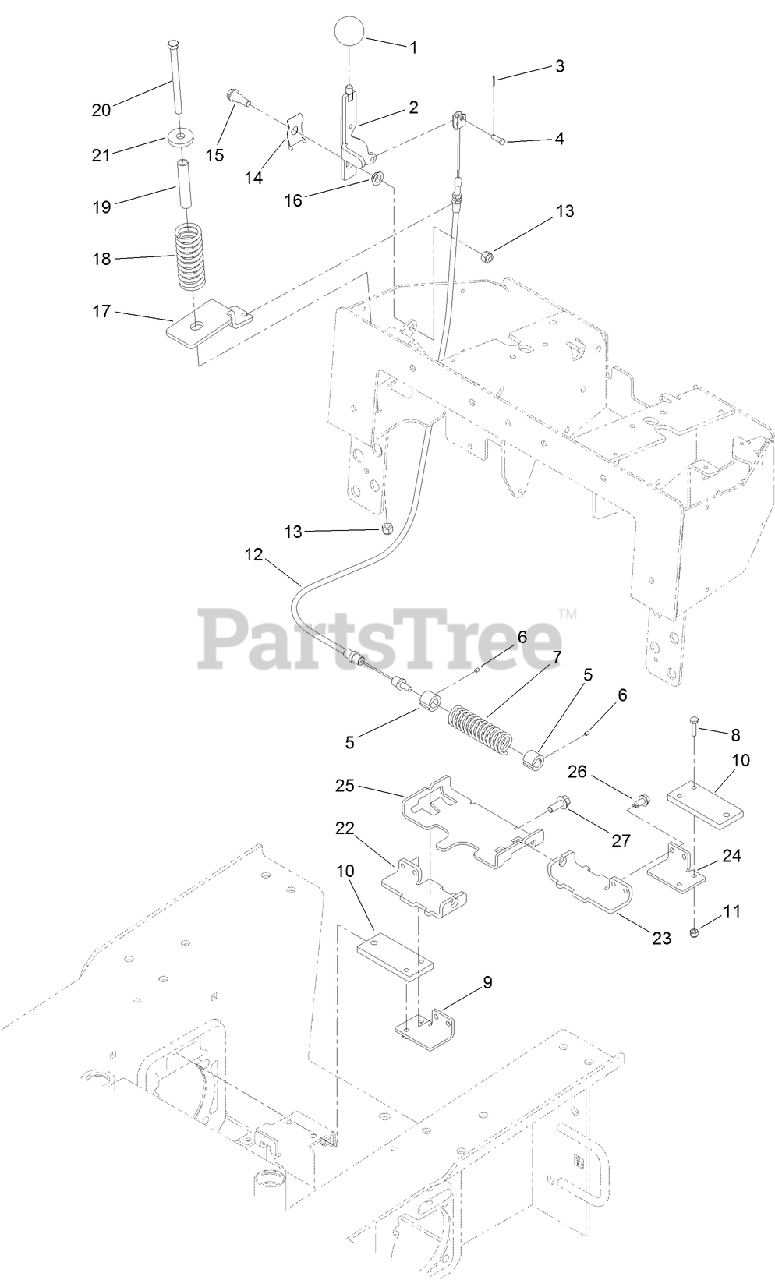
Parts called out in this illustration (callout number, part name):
2	HANDLE-BRAKE
3	PIN-COTTER
4	PIN-CLEVIS
5	Tube-Guide
6	SCREW-HSH
7	SPRING
8	SCREW-HH
9	BAR-LINK, BRAKE RH
10	PLATE-BRAKE
11	NUT-LOCK, NI
12	CABLE-BRAKE
13	NUT-LOCK, NI
14	SPRING-LEAF
15	BOLT-SHOULDER
16	BUSHING-FLANGE
17	BRACKET-CABLE, SPRING
18	SPRING-COMPRESSION
19	SPACER-SPRING
20	SCREW-HH
21	WASHER-HARDENED
22	BRACKET-MOUNTING, BRAKE RH
23	BRACKET-MOUNTING, BRAKE LH
24	BAR-LINK, BRAKE LH
25	SUPPORT-BAR, BRAKE
26	SCREW-HWH
27	SCREW-HHF
